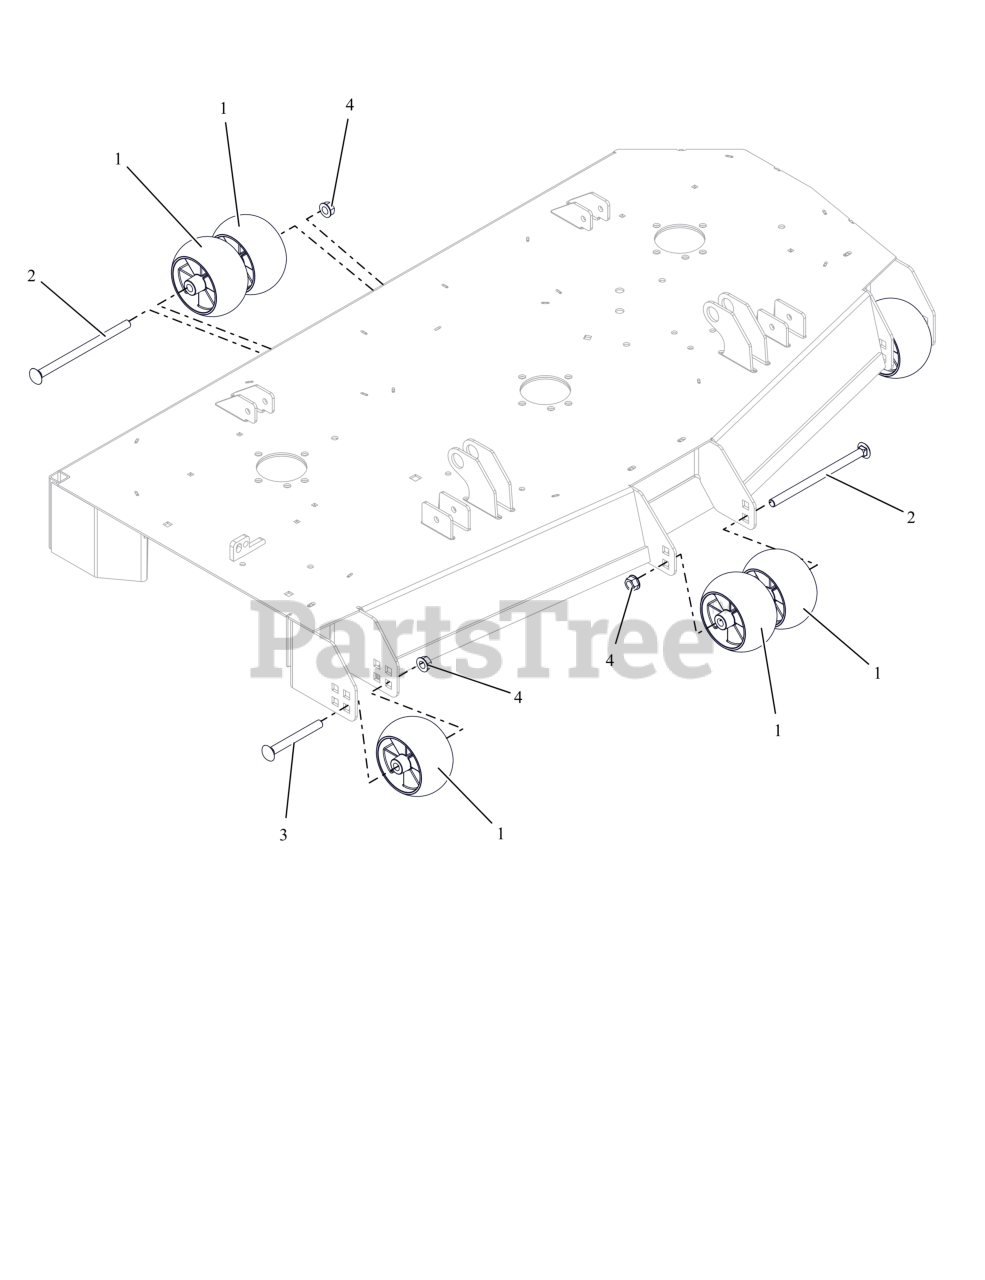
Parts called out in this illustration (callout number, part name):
1	WHEEL, ANTI SCALP - 5X3 CTR W/RIBS
2	BLT,RHSN .50-13X8.00 G5 ZCC NS
3	BLT,RHNS .50-13X4.50 G5 ZCC NS
4	NUT-LK-CTR-FLG .500-13 GG ZCC
